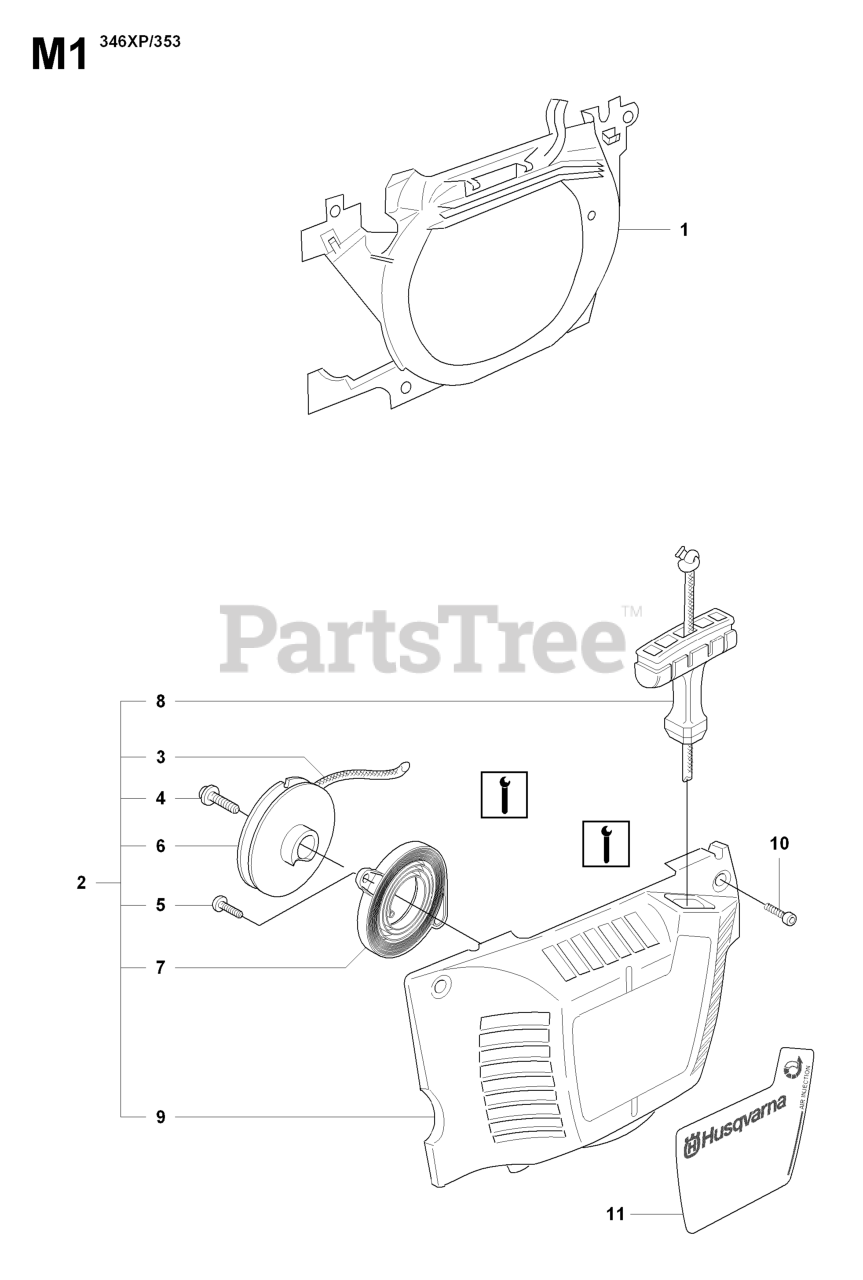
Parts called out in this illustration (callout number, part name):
1	AIR CONDUCTOR
2	STARTER HOUSING ASSY.
3	STARTER ROPE
6	PULLEY
7	RETURN SPRING
8	STARTER HANDLE
9	STARTER HOUSING
10	SCREW.CCRPANMO.M5X19 10.9 TBO
11	DECAL
